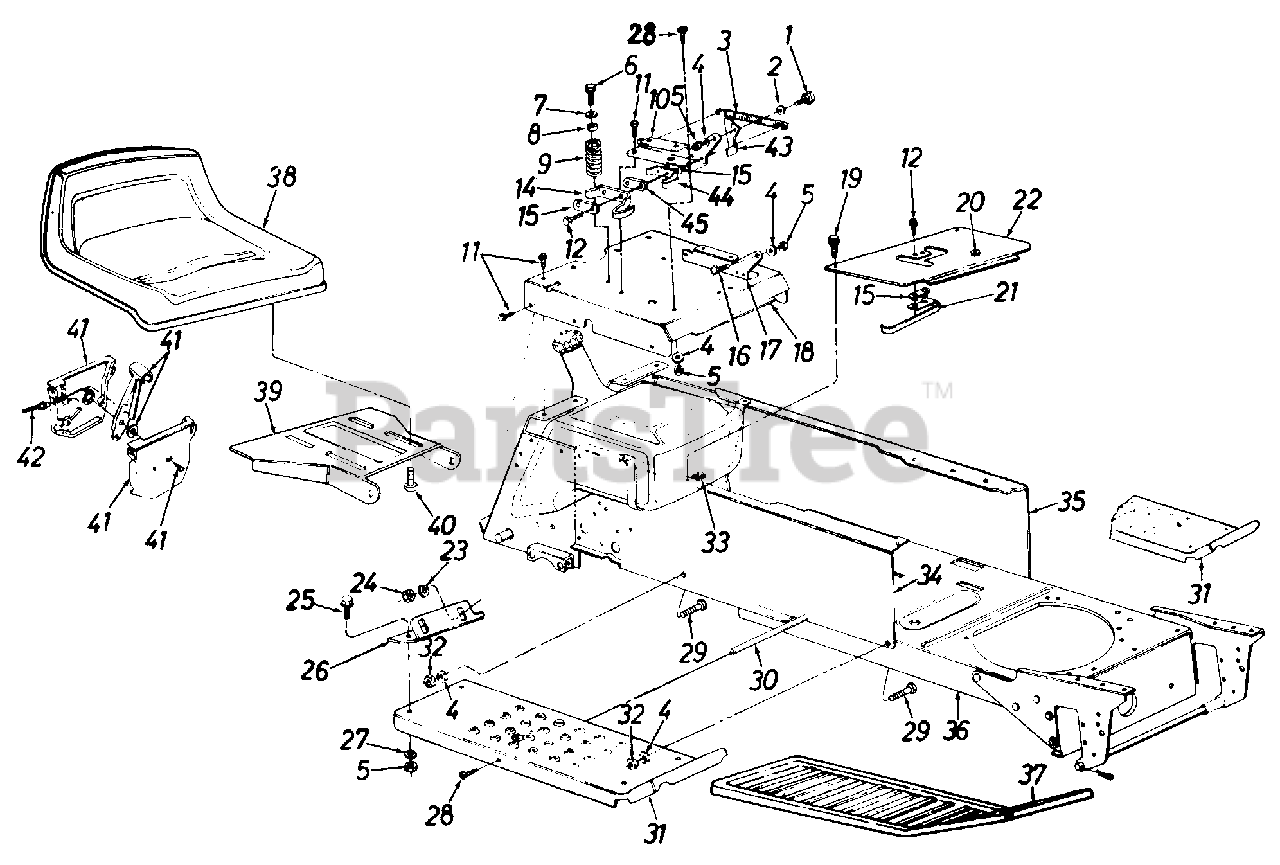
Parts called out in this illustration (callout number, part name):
1	Shld. Bolt .437" Dia. x .162"
2	Spr. Wash. .445" I.D.
3	Ext. Spring 5.31" Lg.
4	L-Wash. 5/16" I.D.
5	Hex Nut 5/16-18 Thd.
6	Hex Wash. Hd. Tap Scr. 5/16-18 x .7" Lg.
7	Fl-Wash. .344" I.D.
8	Bushing
9	Compression Spring
12	Hex Wash. Hd. AB-Tap Scr. #8 x .5" Lg.
14	Spring Switch
15	N Insulator End Plate
16	Shld. Bolt .437" Dia. x .162"
19	Truss Mach. B-Tap Scr. #10 x .5" Lg.
20	Snap Bushing
21	Reverse Safety Switch
22	Shift Cover
23	L-Wash. 1/4" I.D.
24	Hex Nut 1/4-20
25	Hex Bolt 5/16-18 x .75" Lg.
28	Truss Mach. Scr. 5/16-18 x .75" Lg.
29	Rib Neck Bolt 5/16-24 x .75" Lg.
30	Running Board Rod
33	Speed Nut #10Z
34	R.H. Side Frame
35	L.H. Side Frame
36	N Lower Frame
37	Rubber Foot Pad
38	Seat Ass'y.
39	Seat Pivot Bracket
40	Hex Tap Scr. 3/8-16 x .75" Lg.
41	Throttle Control Box Ass'y.
42	Throttle Control Wire 35" Lg.
43	Seat Lift Bracket
44	N Seat Spring Switch
45	N Insulator Center Plate
